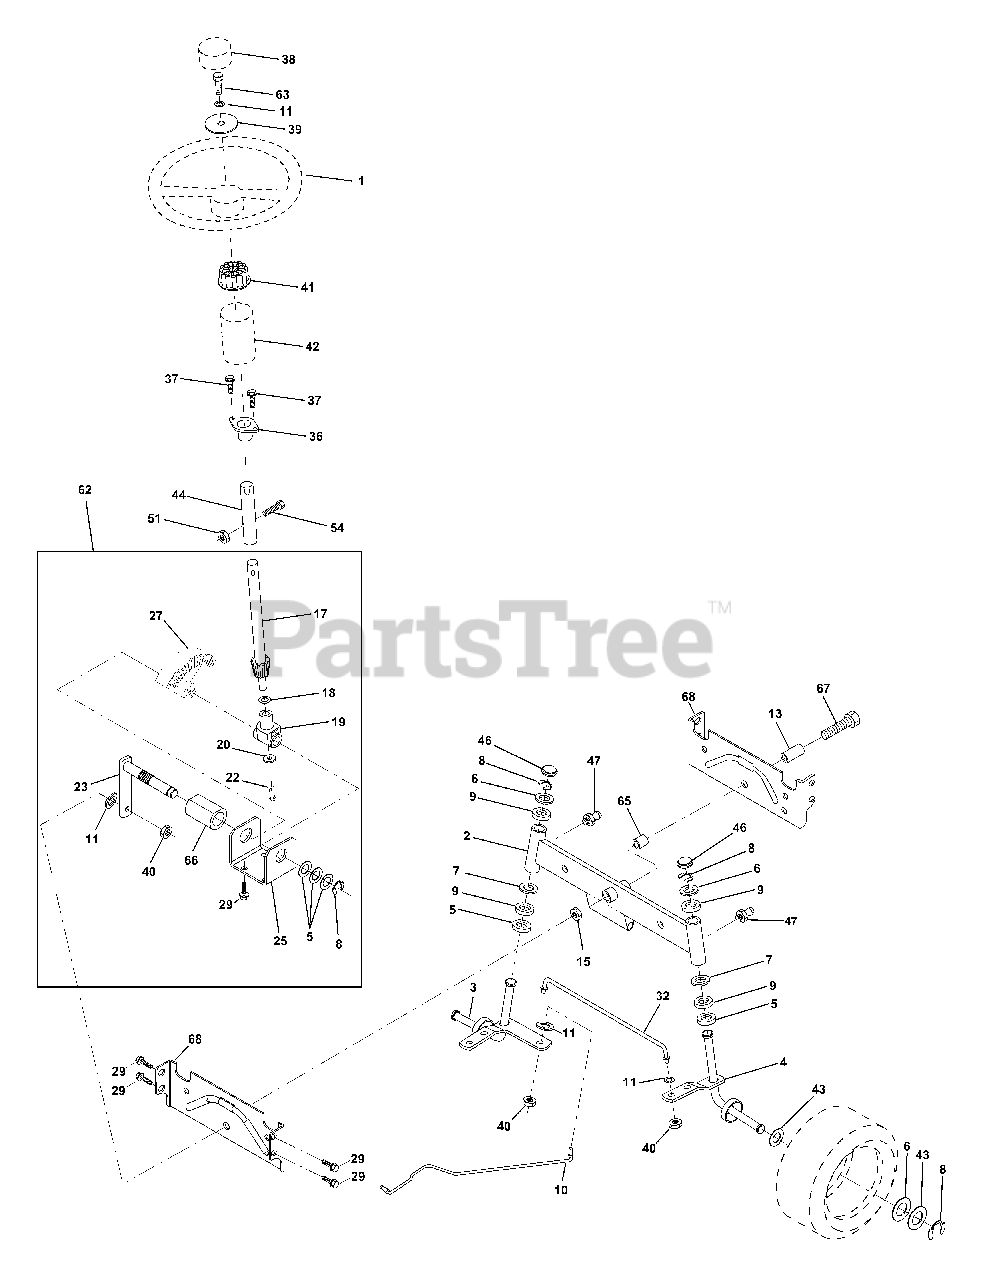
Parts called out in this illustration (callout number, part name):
1	Wheel Steering
2	Axle Front Casting Machined
3	Spindle Asm LH
4	Spindle Asm RH
5	Bearing Race Thrust Harden
6	Washer 25/32 X 1-5/8 X 16 Ga
7	Washer 27/32 X 1-1/4 X 16 Ga
8	Ring Klip #t5304-75
9	Bearing Col Strg Blk
10	Link Drag Extended Cast
11	Washer Lock Hvy Hlcl Spr 3/8
13	Bearing Axle STLT/GT
15	Nut Lock Flange 5/8-11 Unc
17	Shaft Asm Strg
18	Washer Thrust 515x 750x 033
19	Support Shaft
20	Washer Shim 1/4 X 5/8 X 062
22	Screw Hex Sckt 1/4-20 x 5/8
23	Shaft Asm Pittman
25	Bracket Steering
27	Gear Sector
29	Screw Thdrol 3/8-16x3/4 Ty-tt
32	Rod Asm Tie Ball Adj. VGT
36	Bushing Strg
38	Insert Cap Strg Wh Au
39	Washer 13/32 X 2-3/8 X 8 Ga
40	Lock nut
41	Adaptor Wheel Strg
42	Boot Steering Shaft
43	Washer 25/32 X 1 1/4 X 16 Ga
44	Extension Steering Shaft LR/LT
46	Cap Spindle Fr Top Blk
47	Fitting Grease
51	Nut Lock Hex w/Ins 5/16-18
54	Bolt Fin Hex 5/16-18 Unc x 1-1/4
62	Kit, Steering Assembly Svc
63	Bolt Fin Hex 3/8-16unc x 1 Gr. 5
65	Spacer Axle
66	Bearing Arm Pittman
67	Bolt, Fin Hex 5/8-11 UNC x 2-3/4
68	Brace, Axle
